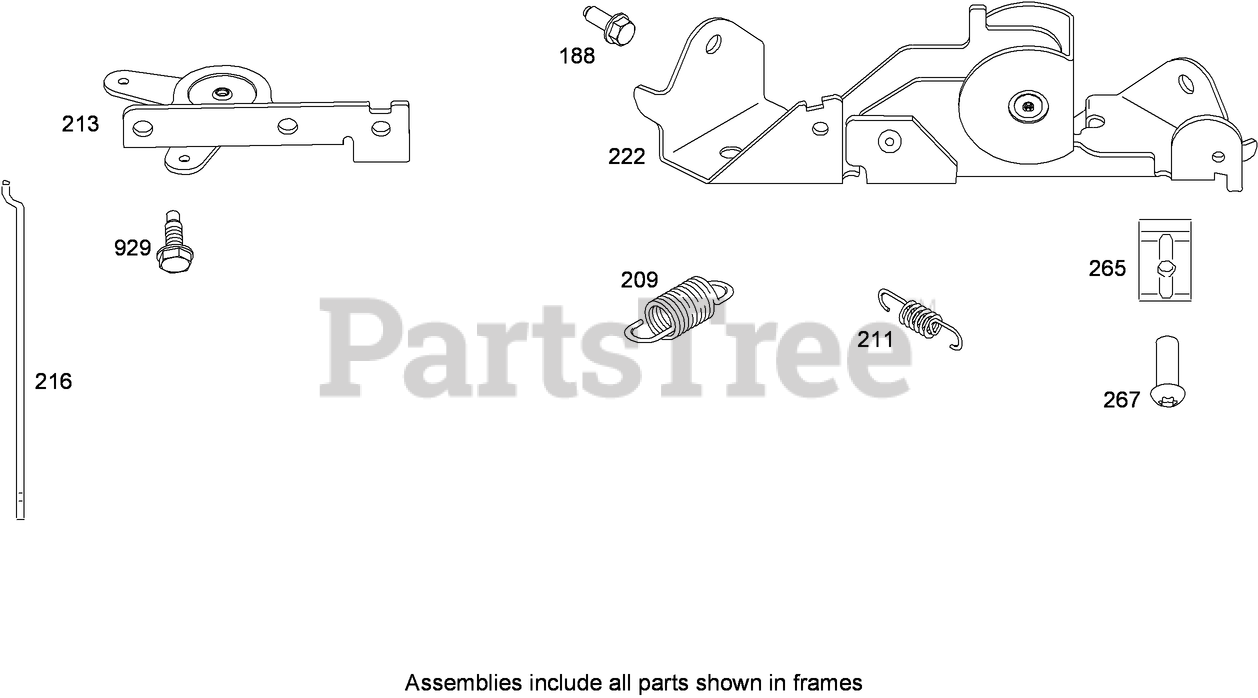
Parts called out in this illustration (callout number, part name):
188	Screw
209	Spring-Governor (Light Green)
211	Spring-Idle, Governed
213	Bracket-Control, Choke
216	Link-Choke
222	Bracket-Control
265	Clamp-Casing
267	Screw
929	Screw (Choke Control Bracket)
